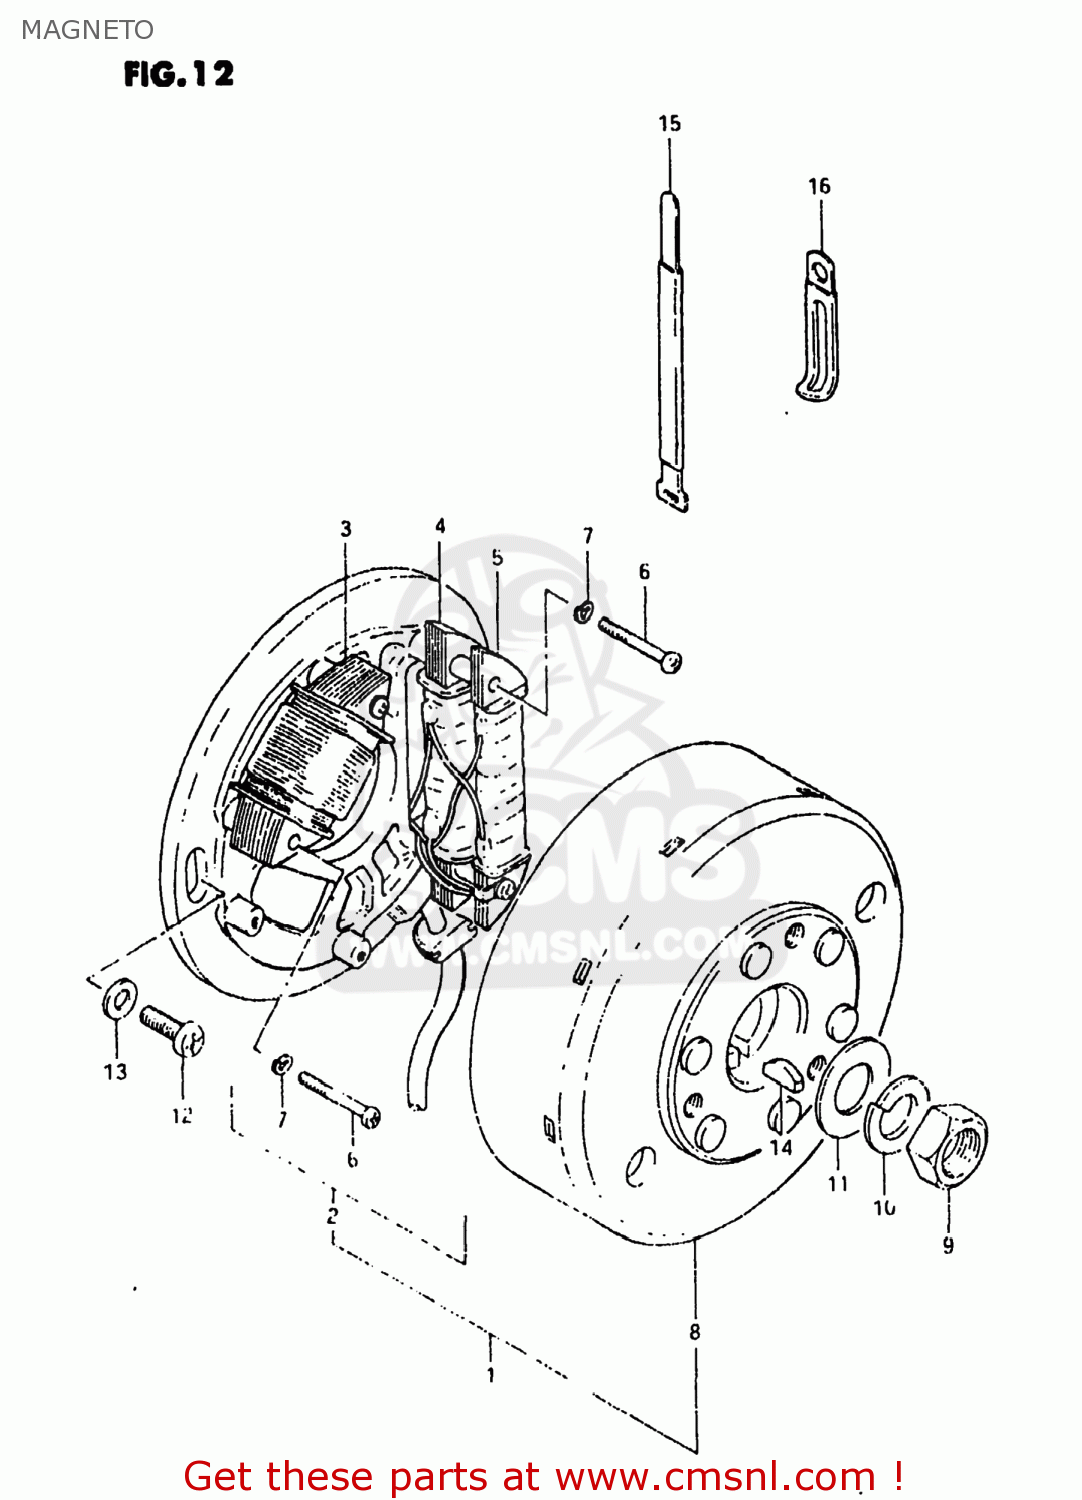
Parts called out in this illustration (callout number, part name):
1	MAGNETO ASSEMBLY
2	STATOR ASSEMBLY
3	COIL,LIGHTING
4	COIL
5	COIL,PRIMARY
6	SCREW (4X30)
7	LOCK WASHER
8	ROTOR ASSEMBLY
9	NUT (10MM)
10	LOCK WASHER
11	WASHER
12	SCREW
13	WASHER
14	KEY 4MM
15	CLAMP L:110
16	CLAMP
